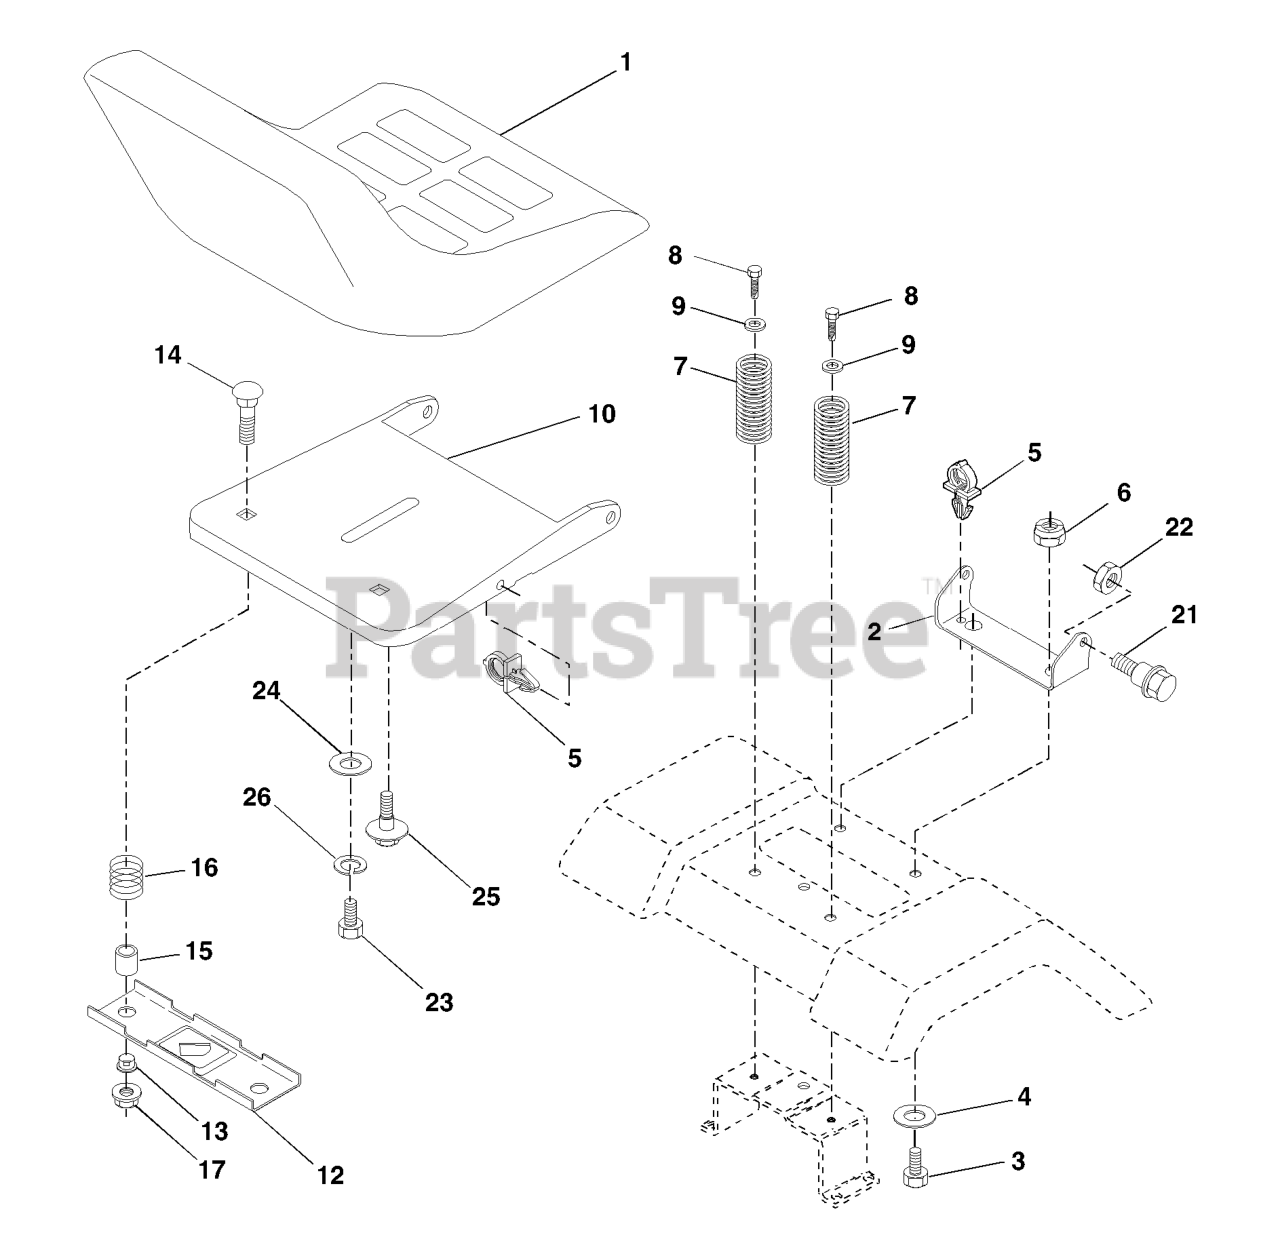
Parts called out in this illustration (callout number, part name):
1	SEAT
2	SEAT PIVOT BRKT
3	BOLT, HEX 3/8-16X1
6	NUT
7	SPRING COMPRESSION
8	SCREW 3/8-16X1
9	WASHER
10	PAN, SEAT
12	BRKT SWITCH
14	BOLT.ROUND.HEAD.SQUARE.NECK
15	SPACER SPLIT 28X.96
17	NUT T
21	BOLT.SHOULDER.5/16-18
22	NUT.71038.31-18.HEX.NYLOCK
23	BOLT.HEX.BLACK
25	BOLT,SHOULD
26	LOCKWASHER
